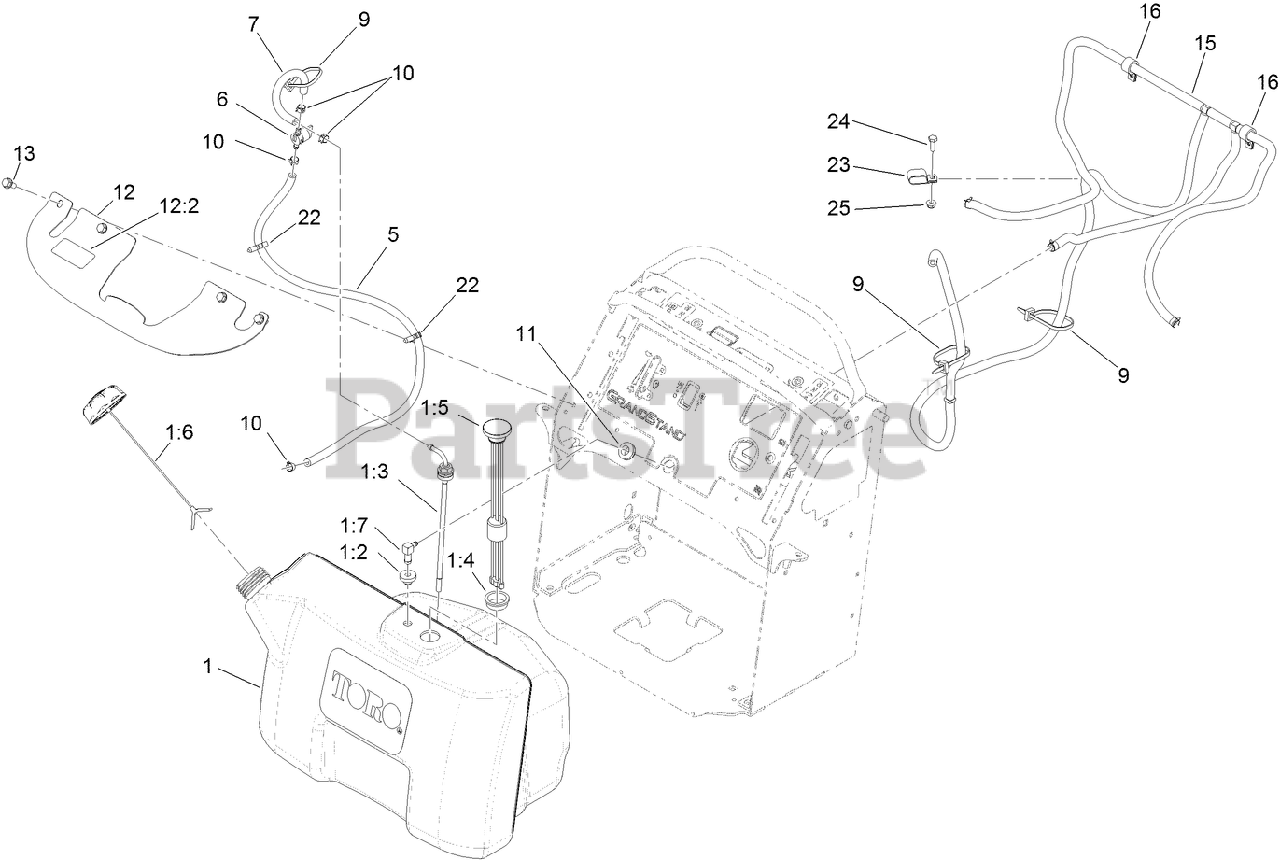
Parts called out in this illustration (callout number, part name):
1	TANK ASM
1:2	BUSHING
1:3	ELBOW-90 DEG
1:4	GROMMET
1:5	GUAGE-FUEL
1:6	CAP-FUEL, RATCHETING
1:7	FITTING-FUEL, BULKHEAD
5	HOSE-FUEL
6	VALVE-FUEL
7	HOSE-FUEL
9	TIE-CABLE
10	CLAMP-HOSE
11	GROMMET
12	BRACKET-TANK
12:2	DECAL-FILL, FUEL
13	SCREW-HWHTF
15	VENT HOSE ASM
16	CLAMP-CABLE
22	CLIP-HARNESS
23	CLAMP-TUBE, DOUBLE
24	SCREW-HH
25	NUT-HF
